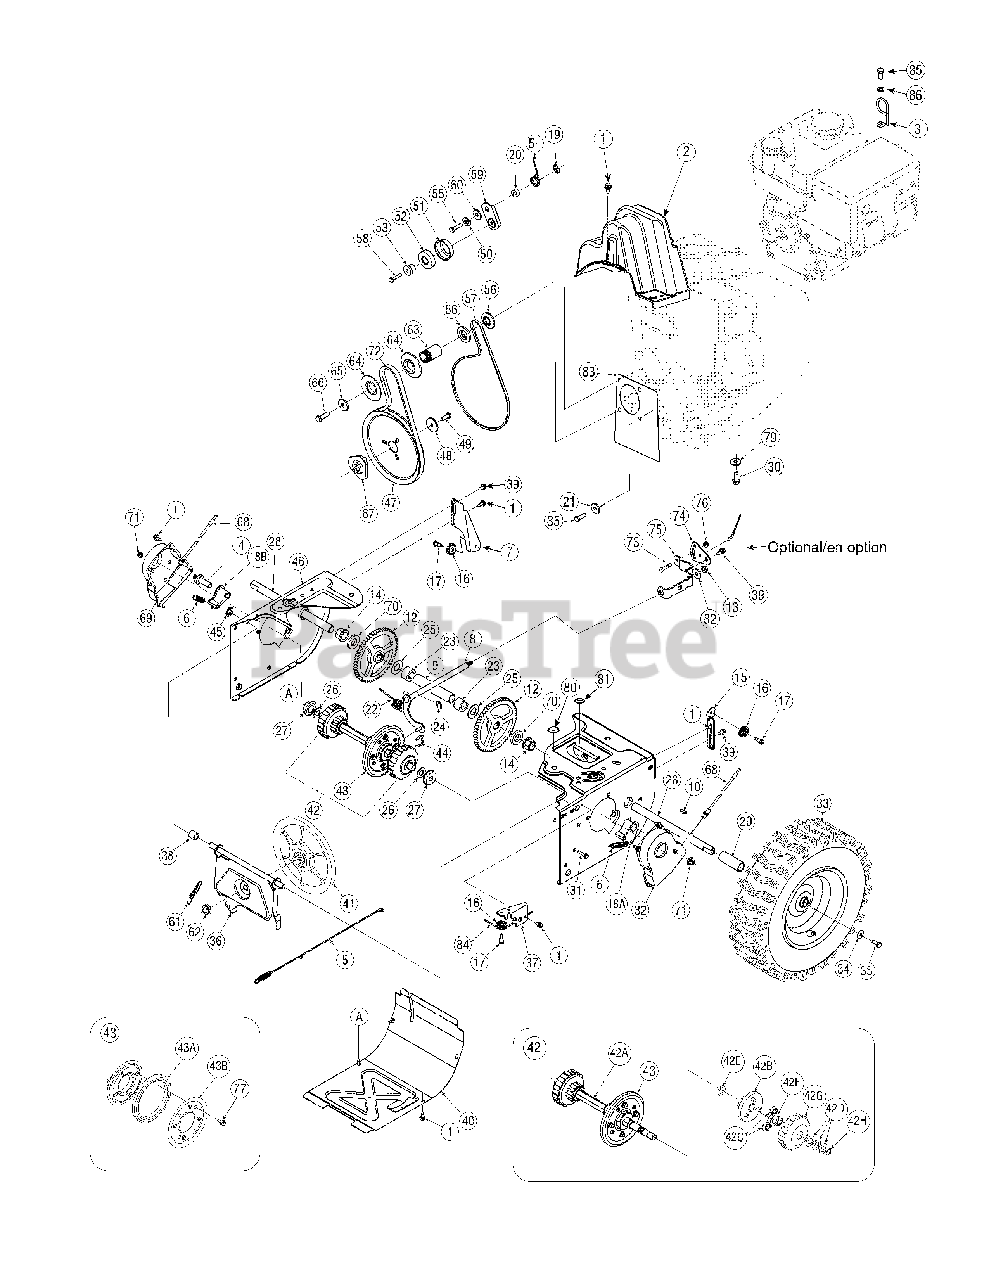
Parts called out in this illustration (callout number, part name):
1	Hex Wash Hd TT Scr. 1/4-20 x .625
2	Belt Cover (w/4 Way Chute Control)
2	Belt Cover (Std.)
3	Cable Control Wire
4	Drive Shaft Actuator
5	Drive Clutch Cable 44.83" Lg.
6	Extension Spring .5 OD x 1.71 Lg.
7	Guide Bracket - Drive Cable
8	Shift Rod Ass’y
9	Axle Support Tube
10	#9 HI-Pro Key 3/16 x 3/4 Dia HT
12	Gear, 56T
13	Flange Lock-Nut 5/16-18 Gr. F Nylon
14	Hex. Flange Bearing.751" ID
16	Cable Guide Roller
17	Hex Shld.Scr.1/4-28 x .375
18A	Dogg Assembly - LH
18B	Dogg Assembly - RH
20	Spacer .340 x .750 x .360" Lg.
21	Shoulder Spacer
22	Torsion Spring .750 ID x .968" Lg.
24	Retaining Ring
25	Flat Washer .760 ID x 1.49 OD
26	Flat Washer .580 x 1.125 x .080
28	Axle
30	Hex Wash HD Tap Scr 3/8-16 x .88
31	Hex Bolt 1/4-20 x 1.00
34	Cupped Washer .345 ID x .88 OD x .060
35	Hex L-Bolt 5/16-24 x .75 Gr. 5
38	Spacer .513 ID x 1.0
39	Shoulder Screw .373 x .105:TT 1/4-20
41	Friction Wheel Disc Assembly
42	Drive Shaft Assembly (w/o Friction Wheel Ass'y)
42A	Hex Drive Shaft (500)
42B	Planetary Carrier Ass'y
42D	Flat Washer .58 x 1.12 x .02
42E	Flat Washer 5/8 ID x 1.0 OD
42G	Ring Planetary Gear Ass'y (500)
42H	Retaining Ring 1.56 diam.
43	Friction Wheel Assembly
43A	Friction Wheel Rubber
43B	Friction Plate
44	Retainer Ring
45	Cap Speed Nut 1/4 Rod
48	Flat Washer .34 x 1.50 x .150
49	Hex Bolt 5/16-24 x 0.875
50	L-Wash 5/16 ID
51	Bearing Sleeve
52	Ball Bearing 20 x 47 x 14:6204:DS
54	Torsion Spring .850 ID x .354" Lg.
55	Hex HD. Cap Scr. 5/16-24 x 1.25 Lg.
57	Belt 3/8 X 34.4" Lg.
58	Hex Bolt 1/4-20 x 1.25
59	Wheel Drive Idler Bracket
60	Shoulder Spacer
61	Extension Spring 3/8 OD x 2.50
62	Jam L-Nut 5/8-18 Gr. 5 Nylon
63	Spacer .875 ID x 1.185 OD
64	Pulley Half
65	Flat Washer .40 ID x 1.25 OD x .160
66	Hex Screw 3/8-24 x 1.25
67	Pulley Adapter
68	Steering Cable
71	Flange Lock-Nut 3/8-16 Gr. F Nylon
72	Belt .5 x 35.0" Lg.
73	Hex Bolt 1/4-20 x .62 Gr. 5
76	Flange Lock-Nut 1/4-20 Gr. F Nylon
77	Hex Wash. Hd. TT Scr. 1/4-14 x .625
79	Flat Washer .38 x 1.38 x .125 (Rear left hole)
82	Flat Washer .469 x .875 x .105
84	Auger Clutch Cable 47.23" Lg.
85	Hex. Hd. Cap Scr. M8-1.25:20 Gr. 8
86	Flat Washer .330 ID x .630 OD x .0635
